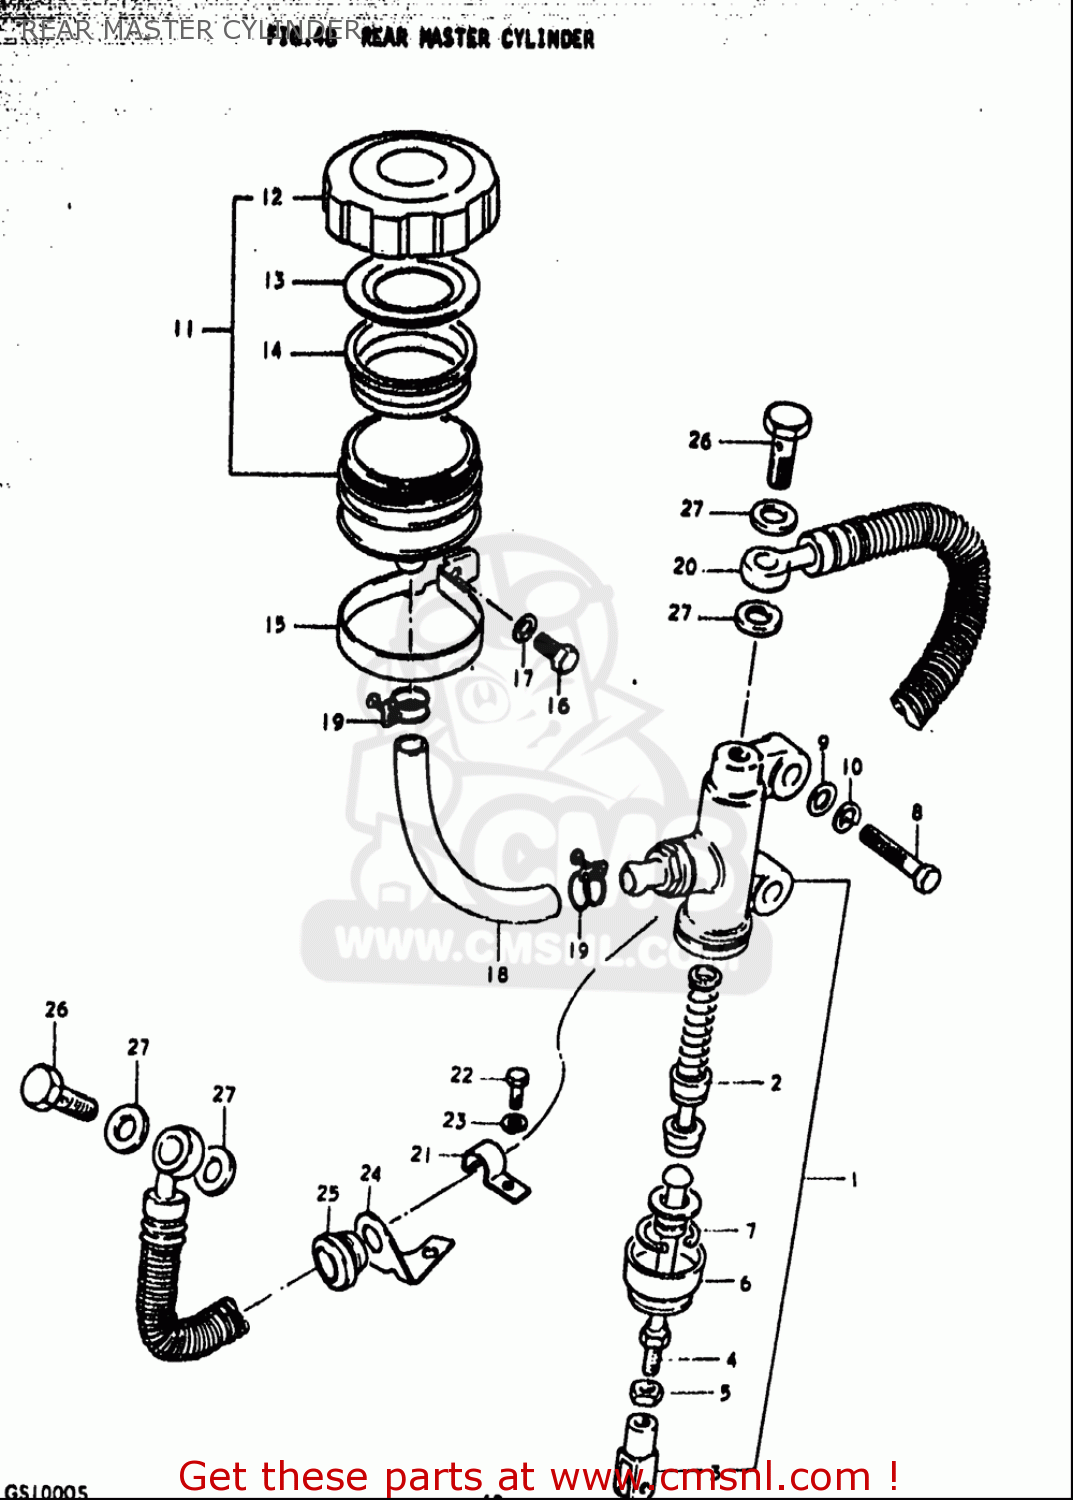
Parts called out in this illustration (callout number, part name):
1	CYLINDER ASSY,RR MASTER
2	PISTON/CUP SET
3	YOKE
4	ROD,PUSH
5	NUT
6	BOOT
7	CIRCLIP
8	BOLT
9	WASHER
10	WASHER,LOCK
11	TANK ASSY,RESERVOIR
12	CAP
13	PLATE,DIAPHRAGM
14	DIAPHRAGM
15	CLAMP
16	BOLT
17	WASHER,LOCK
18	HOSE,BRAKE RESERVOIR
19	CLAMP
22	SCREW(6X8)
23	WASHER,LOCK
24	GUIDE,BRAKE HOSE
25	GROMMET,BRAKE HOSE GUIDE
26	BOLT UNION
27	WASHER(10X15X1.5)
